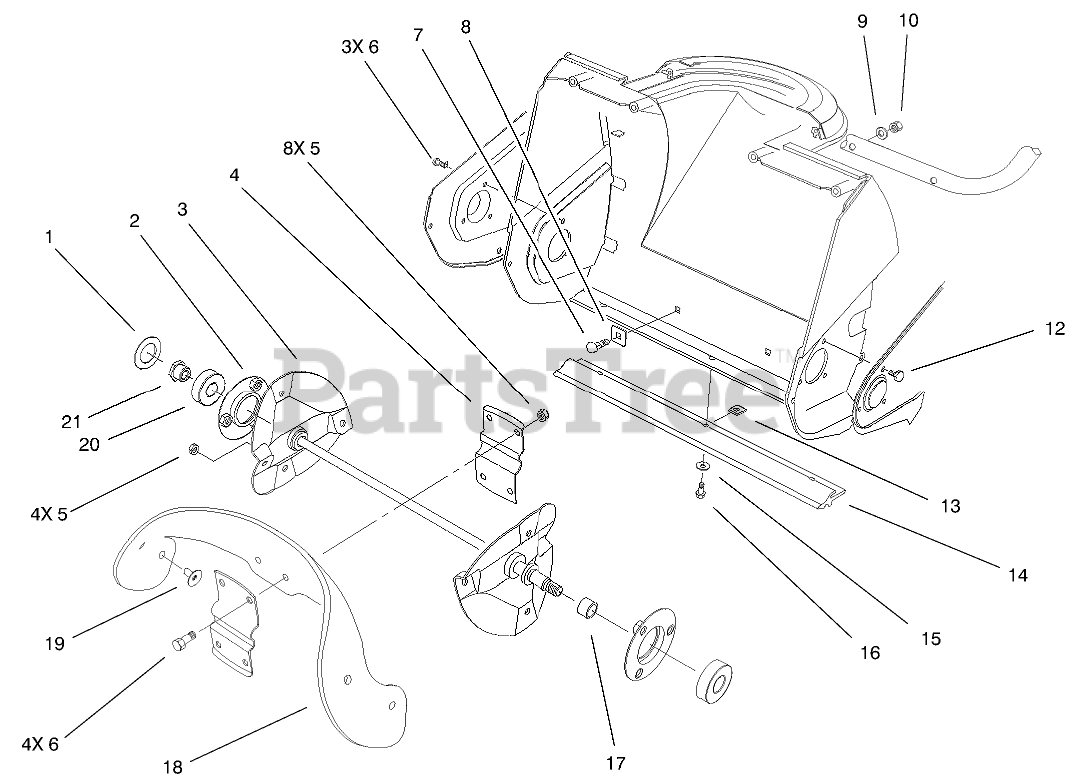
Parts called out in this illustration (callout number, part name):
1	WASHER-RUBBER
2	FLANGE BEARING ASM
3	ROTOR SHAFT ASM
4	SUPPORT-ROTOR
5	NUT-LOCK, NI
6	SCREW-HHF
7	SCREW-CARR
8	WASHER-SQUARE
9	WASHER
10	NUT-LOCK, NI
12	SCREW-HH
13	NUT-CLIP, U
14	SCRAPER
15	WASHER-FLAT
16	SCREW-HWHTF
17	SPACER
18	BLADE-ROTOR
19	SCREW
20	BEARING-BALL
